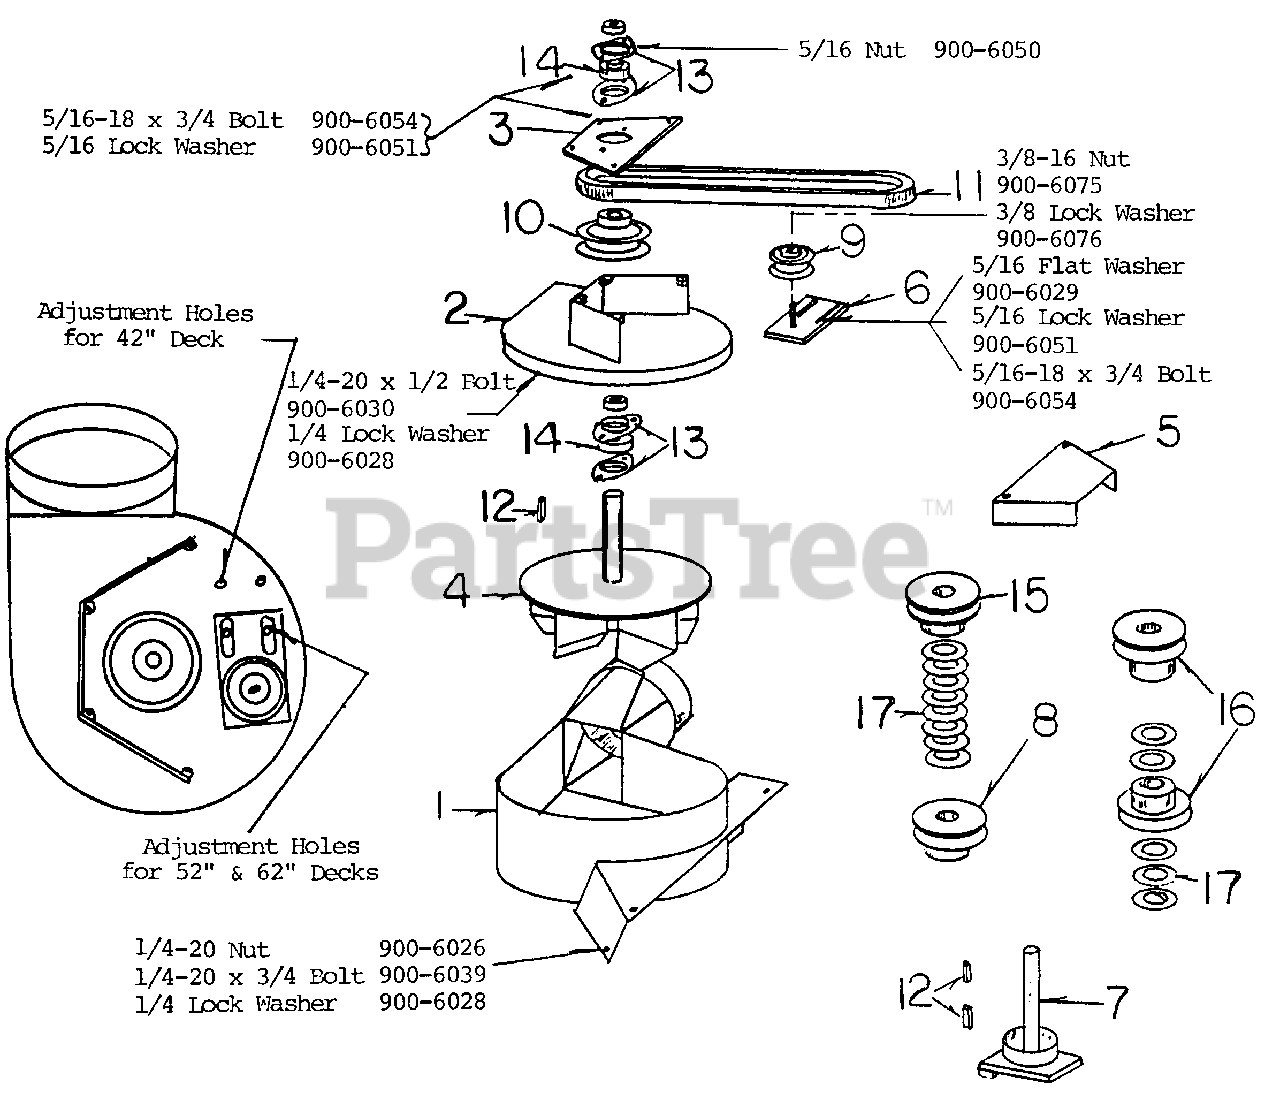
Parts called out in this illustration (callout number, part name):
1	Blower Housing 42" & 52" Deck
3	Blower Bearing Plate
4	Blower Blade Assembly
6	Belt Tightener
7	Long Spindle Shaft 42" & 52" Deck
8	Pulley 42" Deck
9	Idler Pulley
10	Blower Pulley
11	Belt 42" Deck W/l6 0 or 18 HP
12	Key
13	Flange
14	3/4" Bearing w/ lock collar
15	Spindle Pulley 42" Deck w/ 16 or 18 HP
16	Spindle Pulley 52" Deck
